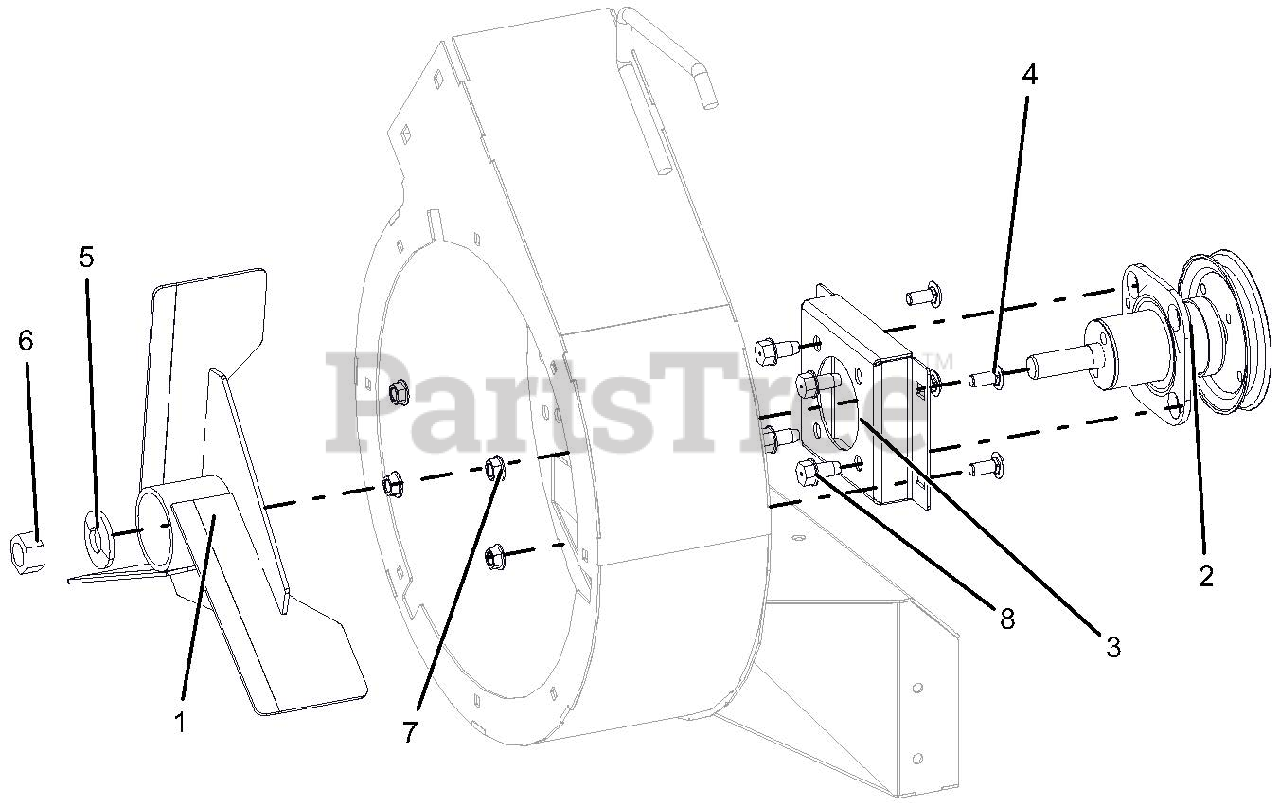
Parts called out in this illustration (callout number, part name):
1	WLDMT, FAN
2	KIT, DECK SPINDLE ASM
3	MOUNT, SPINDLE STANDOFF
4	BLT-RHDSSQNK .31-18X.75 G5YZ
5	WSHR, BLVL .63X1.625X.14
6	NUT-HEX .62-18 YWZC
7	NUT, LK-TOP-FLG .312-18 YWZC
8	SCR-TAP .38-16X.75 HWH TR YWZ
